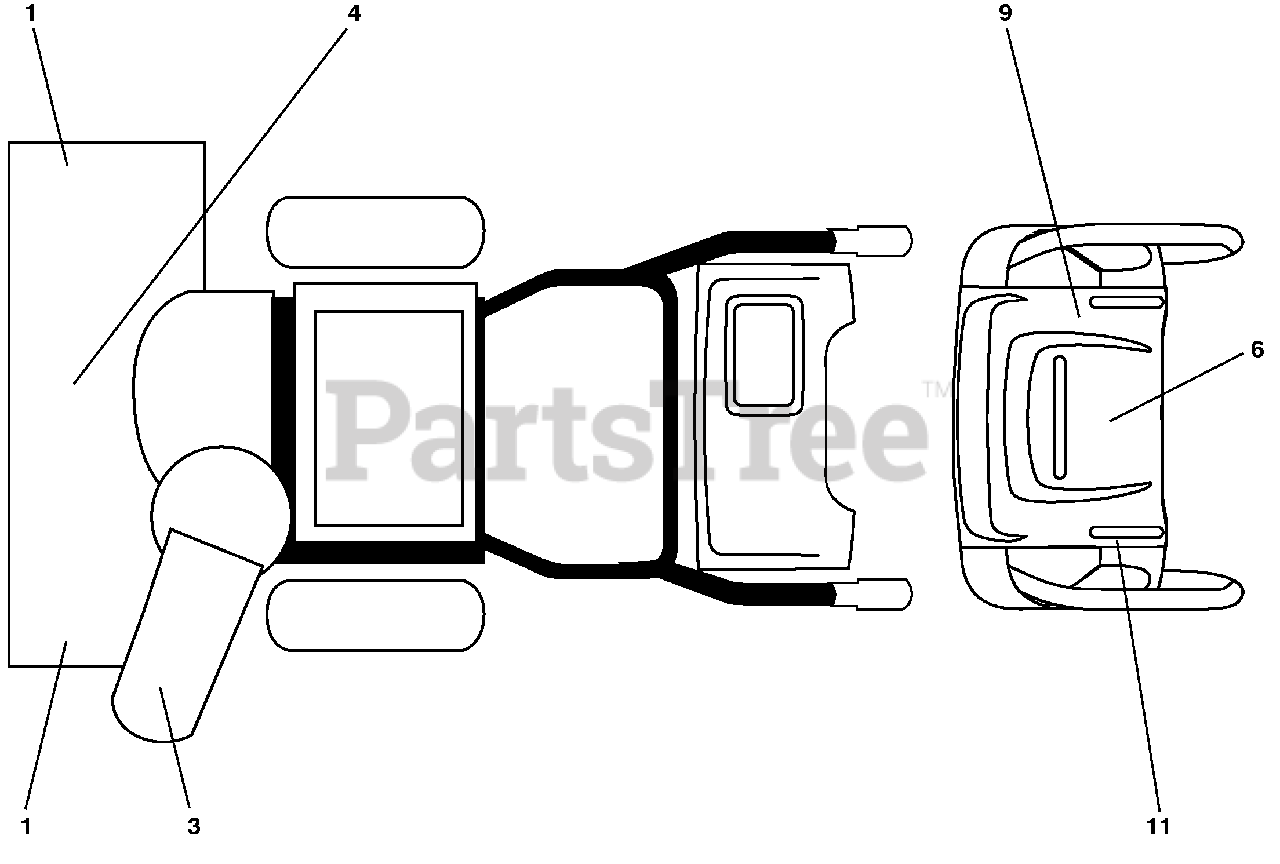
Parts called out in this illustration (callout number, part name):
1	DECAL, DANGER
3	DECAL, DANGER, DEFLECTOR
4	DECAL, DANGER
6	DECAL, INSTRUCTION
9	DECAL, SPEED CONTROL
11	DECAL, TRACT/CLUTCH LEVER
11	OWNER'S MANUAL, ENGLISH
11	OWNER'S MANUAL, FRENCH
